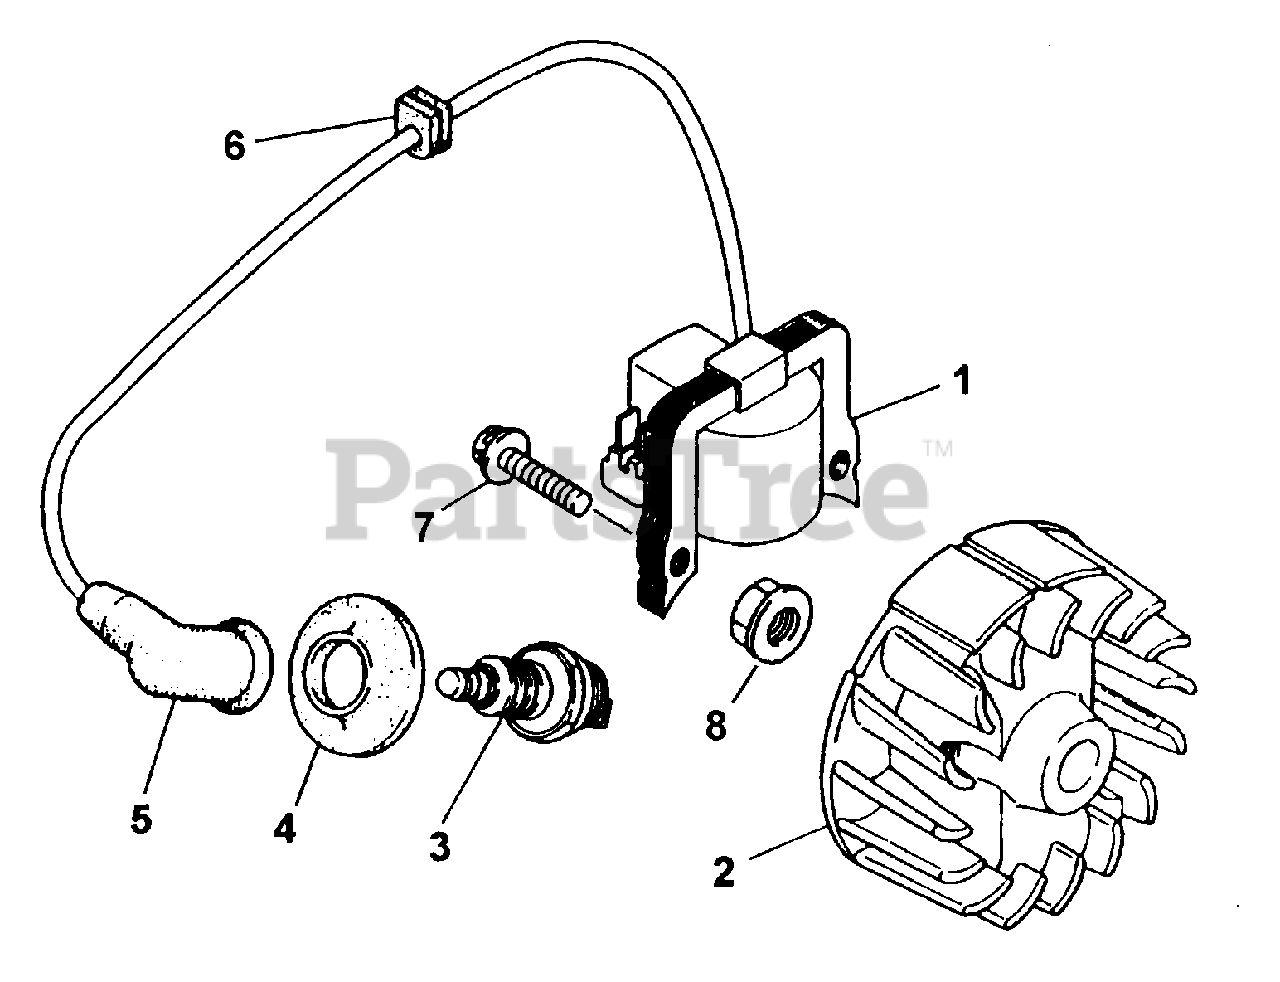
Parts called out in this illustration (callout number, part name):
1	COIL, IGNITION
2	ROTOR w/key
3	SPARK PLUG
4	CAP, GROMMET
5	CAP, PLUG
6	GROMMET, WIRE
7	BOLT & WASHER
8	NUT
